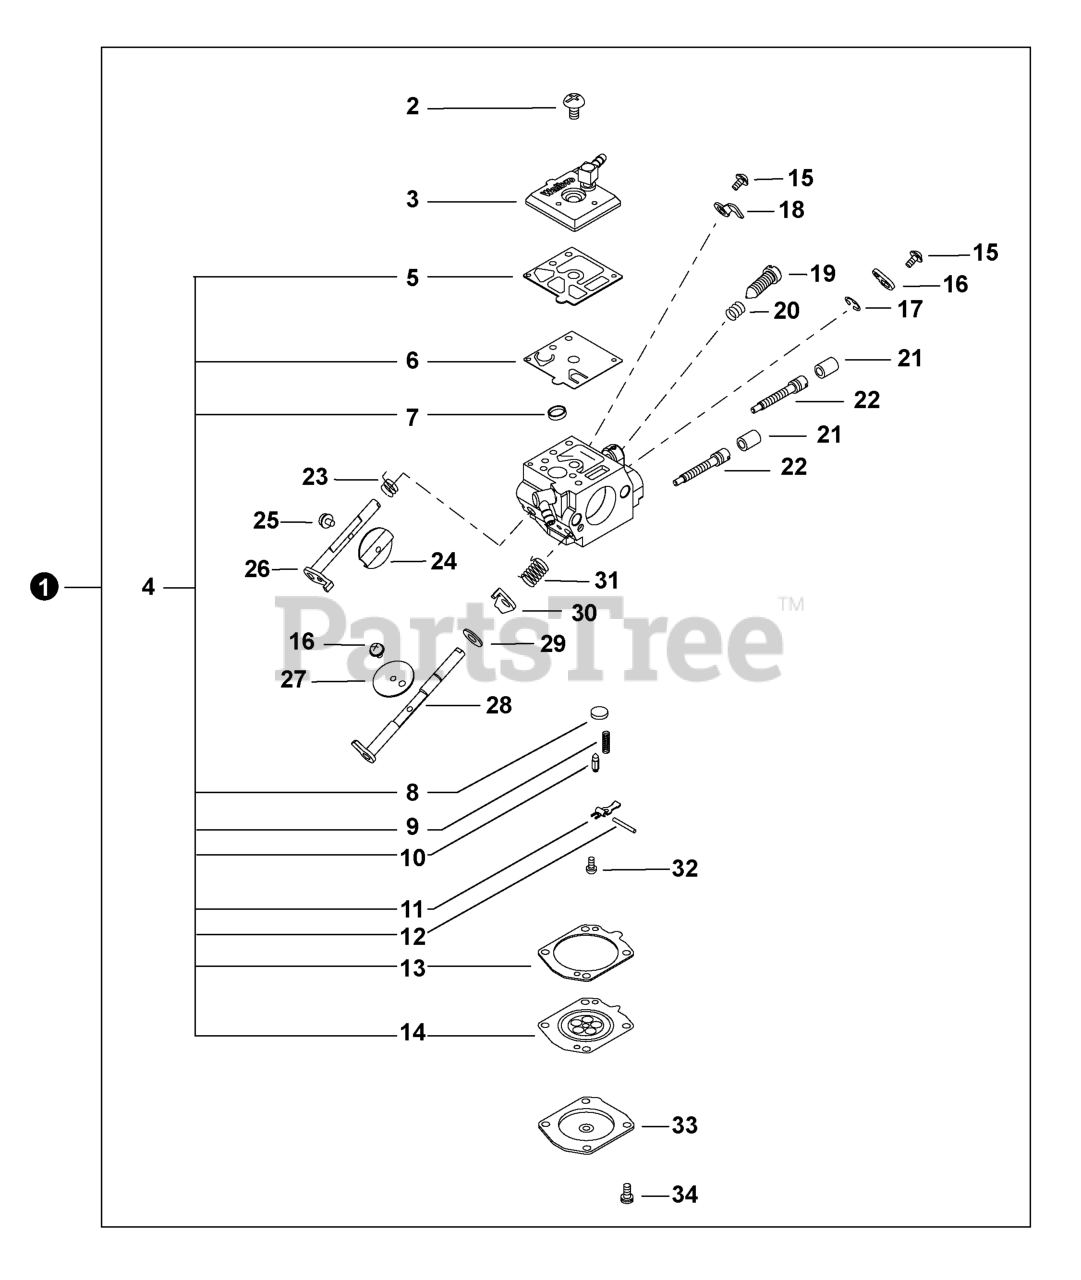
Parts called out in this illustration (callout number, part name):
1	CARBURETOR – HDA-343
2	SCREW
3	COVER, FUEL PUMP
4	REPAIR KIT, CARBURETOR
5	GASKET, FUEL PUMP
6	DIAPHRAGM, FUEL PUMP
7	SCREEN, FUEL INLET
8	PLUG, WELCH
9	SPRING, METERING LEVER
10	VALVE, INLET NEEDLE
11	LEVER, METERING
12	PIN, METERING LEVER
13	GASKET, METERING DIAPHRAGM
14	DIAPHRAGM, METERING
15	SCREW
16	LEVER, THROTTLE
17	E-RING
18	STOP, THROTTLE
19	SCREW, IDLE ADJUST
20	SPRING, IDLE ADJUST
21	CAP, LIMITER
22	NEEDLE, MIXTURE
23	SPRING, THROTTLE RETURN
24	VALVE, THROTTLE
25	SCREW
26	SHAFT ASSY, THROTTLE
27	VALVE, CHOKE
28	SHAFT ASSY, CHOKE
29	WASHER
30	LEVER, FAST IDLE
31	SPRING, CHOKE RETURN
32	SCREW
33	COVER, DIAPHRAGM
34	SCREW
